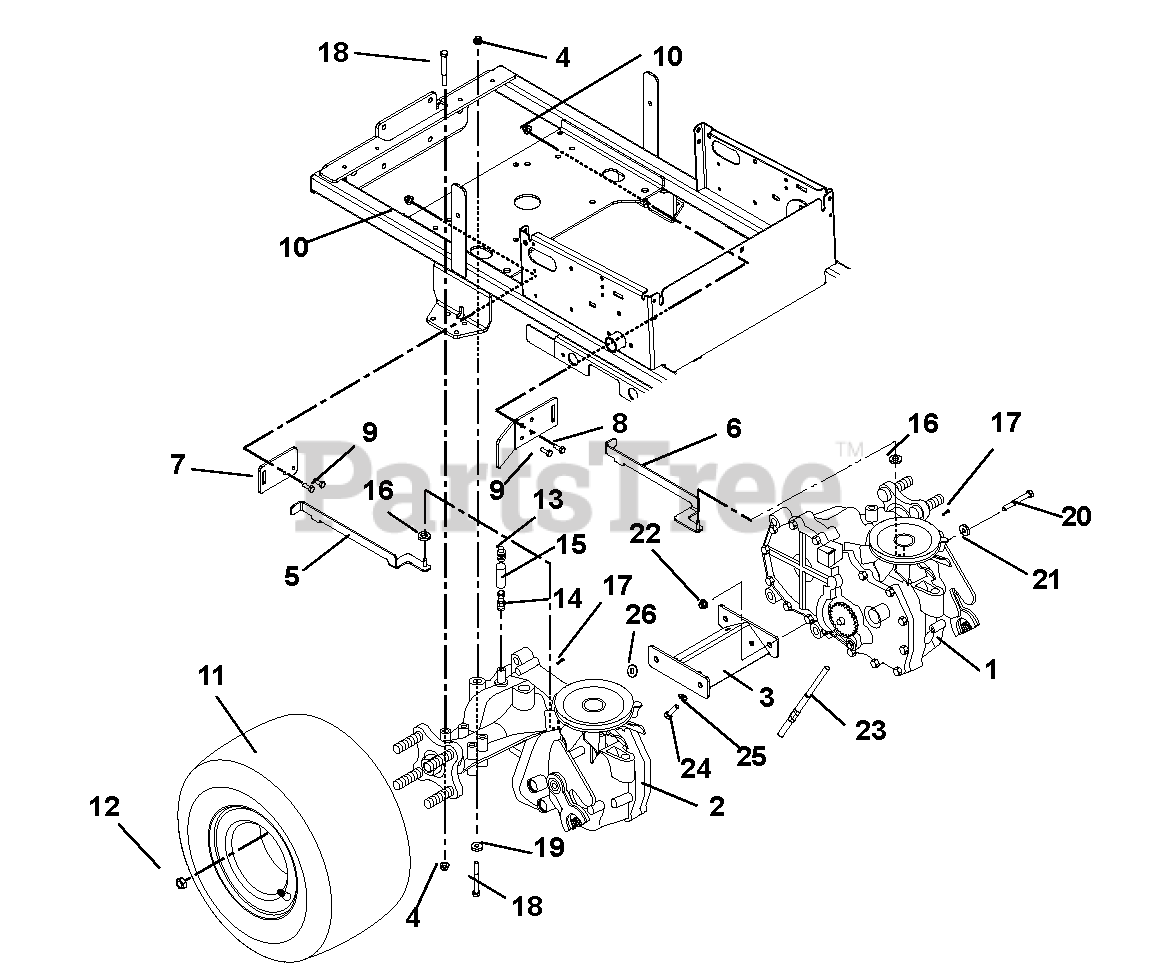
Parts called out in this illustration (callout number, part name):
1	EZT, Left Hand Transaxle-Hydrogear (For service please contact Hydro-Gear)
2	EZT, Right Hand Transaxle-Hydrogear (For service please contact Hydro-Gear)
3	Weldment, Transaxle Support
4	Nut 5/16-18 Flange Nyloc
5	Weldment, Dump Valve (Right Hand)
6	Weldment, Dump Valve (Left Hand)
7	Bracket, Dump Valve
8	Clutch Stop
9	Bolt, Hex .25-20 x .75 Grade 5
10	Nut, Locking Nylon .250-20
11	Assembly, Tire/Wheel 18 x 6.5-8 CTR
12	Nut, Lug .50-20
13	Cap, Vent .50
14	Fitting, Straight .50
15	Hose, Vent
16	Washer, Flat Steel .265 x .50 x .087
17	Pin, Hair, Internal .06 x .18 x .77
18	Bolt, Hex .31-18 x 2.75
19	Washer, Flat Steel .328 x .87 x .179
20	Bolt, Hex .38-16 x 2.50 Grade 5
21	Washer, Flat Steel .406 x 1.00 x .188
22	Nut, .38-16 Nyloc Flange
23	Rear Belt Finger
24	Bolt, Hex .31-18 x 1.00 Grade 5
25	Washer, Locking .31 x .078 Regular
26	Washer, Flat Steel .38 x .875 x .083
